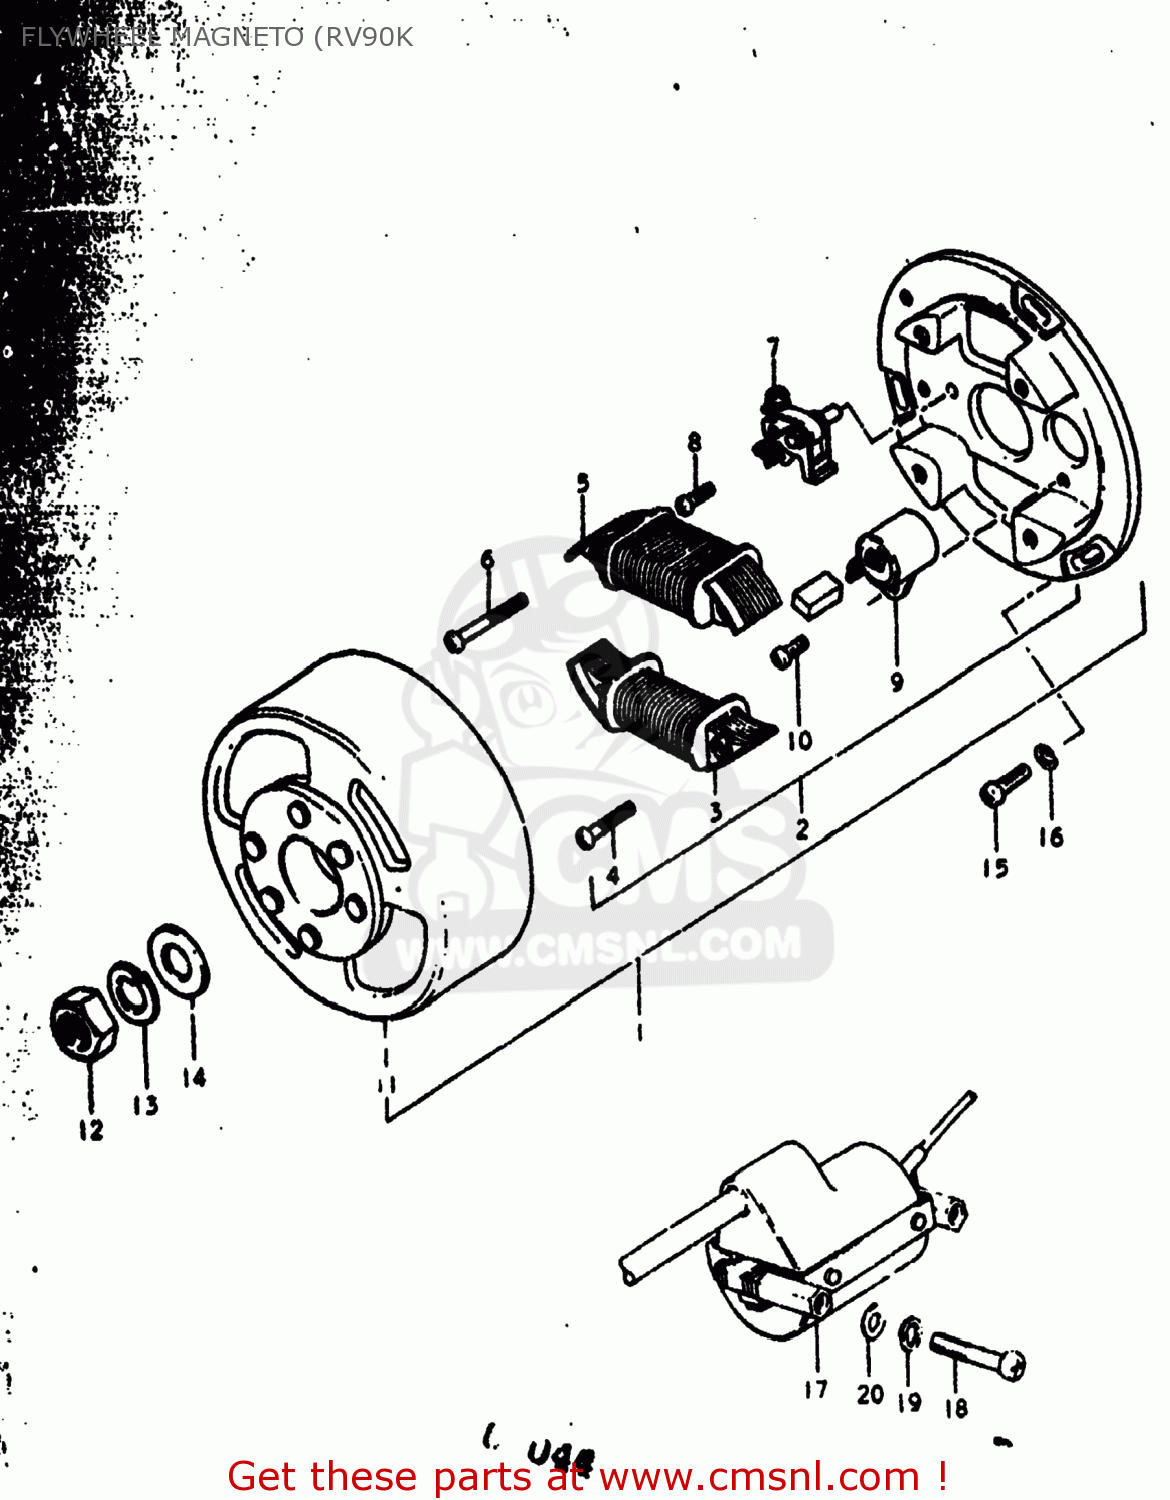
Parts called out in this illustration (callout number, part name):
1	MAGNETO ASSEMBLY
2	STATOR ASSEMBLY
3	COIL,LIGHTING
4	SCREW
5	COIL
6	SCREW
7	POINT ASSEMBLY,CONTACT
8	.SCREW
9	CONDENSER
10	SCREW
11	ROTOR ASSEMBLY
12	NUT (10MM)
13	LOCK WASHER
14	WASHER
15	SCREW
16	WASHER
17	COIL ASSEMBLY,IGNITION
18	Screw
19	LOCK WASHER
20	WASHER
